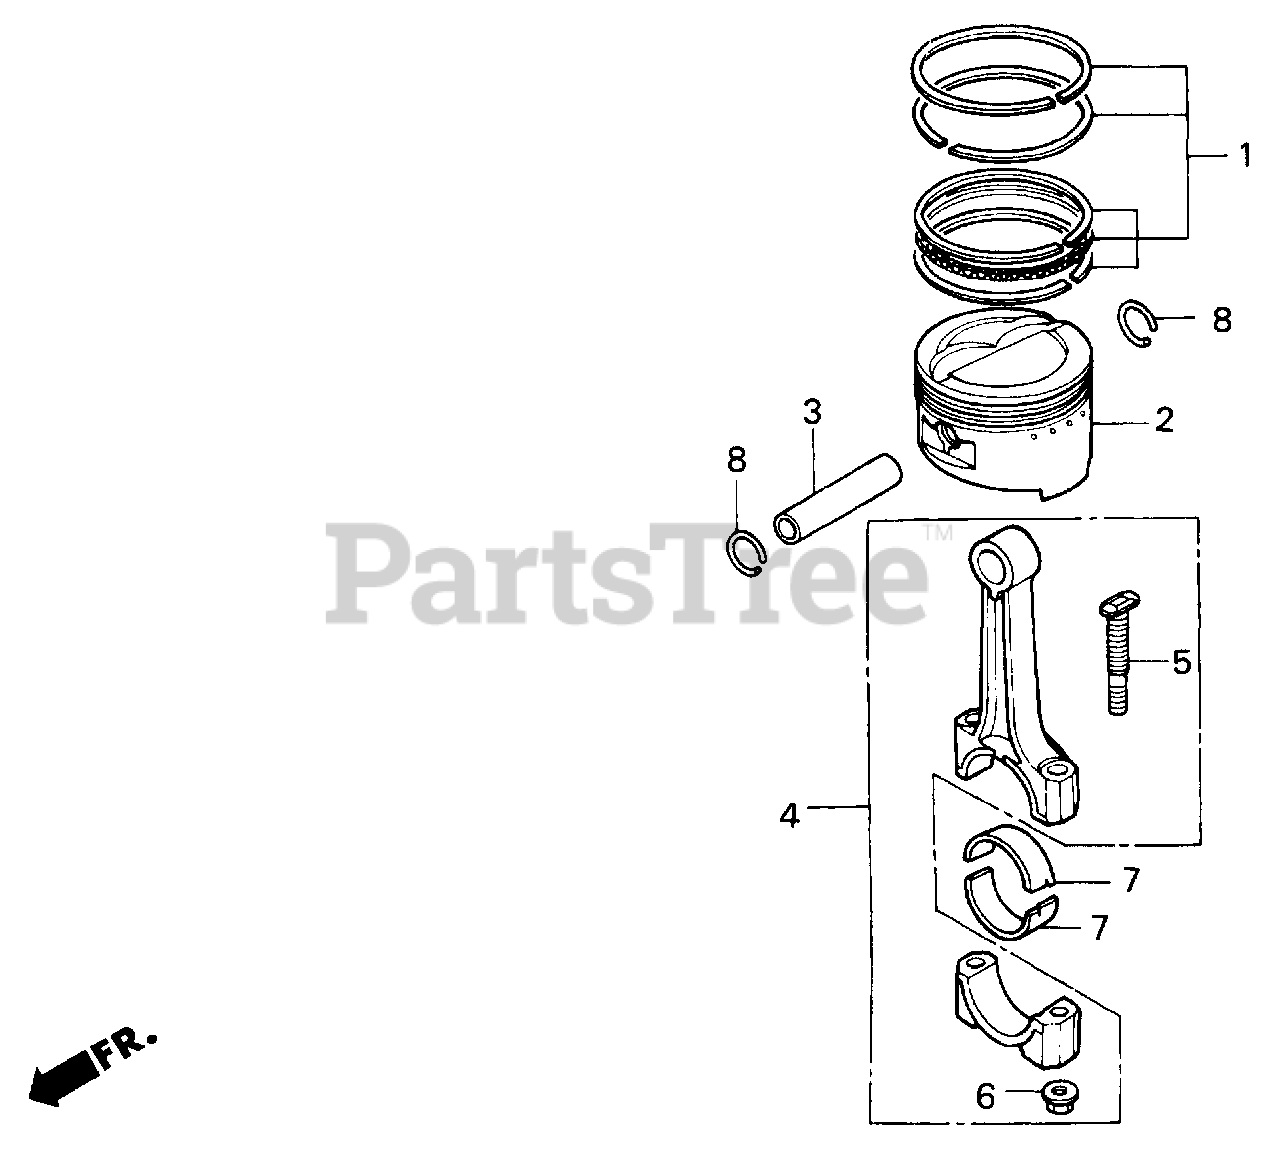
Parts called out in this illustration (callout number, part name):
1	RING SET, PISTON (STD)
1	RING SET, PISTON (OS 0.25)
1	RING SET, PISTON (OS 0.50)
2	PISTON (STD)
2	PISTON (OS 0.25)
2	PISTON (OS 0.50)
3	PIN, PISTON
4	ROD ASSY., CONNECTING
5	BOLT, CONNECTING ROD
6	NUT, CONNECTING ROD
7	BEARING A, CONNECTING ROD (BLACK)
7	BEARING B, CONNECTING ROD (BROWN)
7	BEARING C, CONNECTING ROD (GREEN)
7	BEARING D, CONNECTING ROD (YELLOW)
7	BEARING E, CONNECTING ROD (RED)
8	CLIP, PISTON PIN (14MM)
